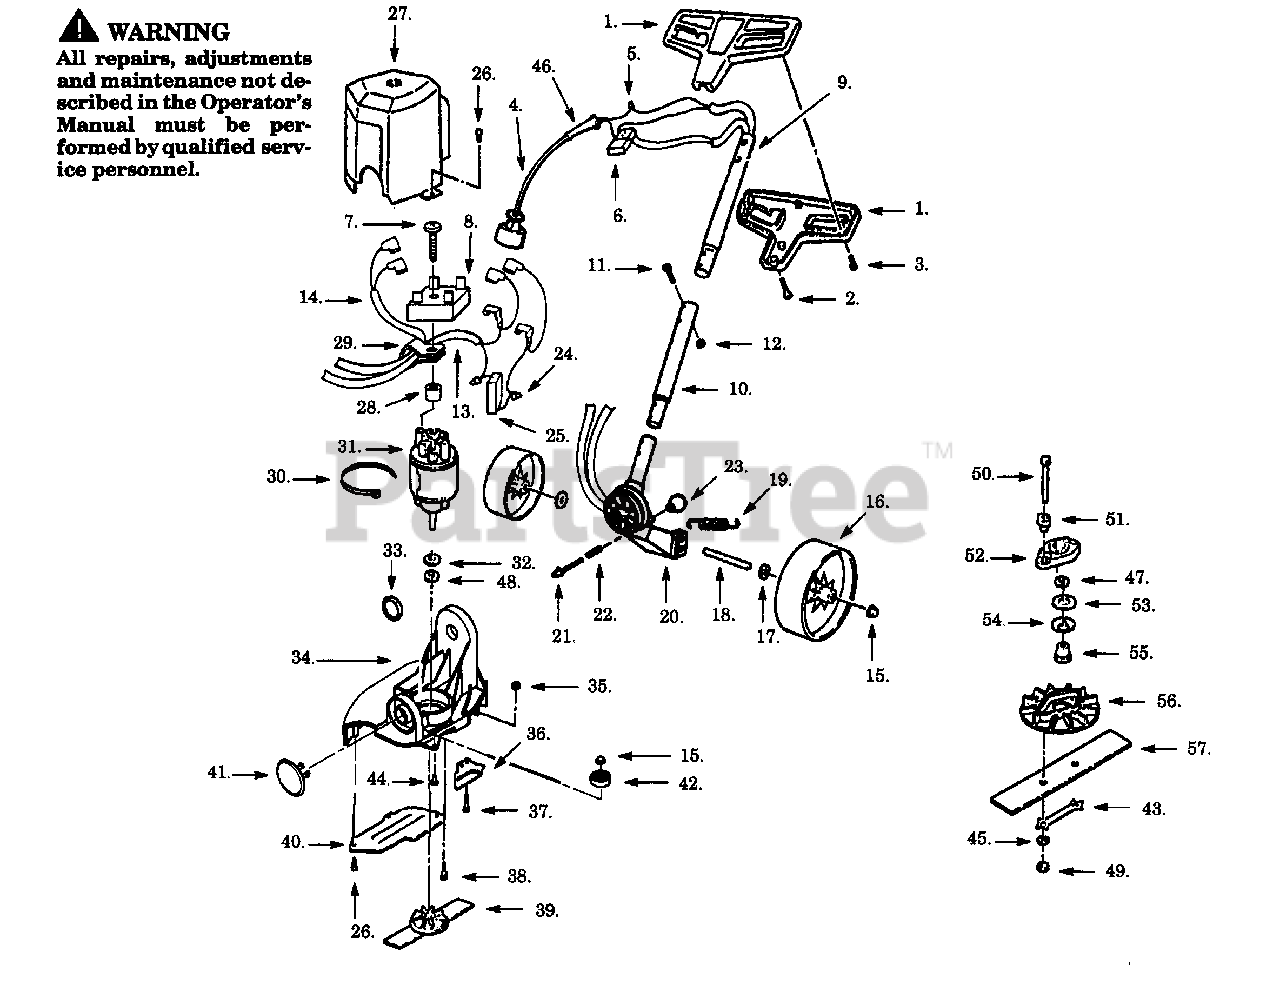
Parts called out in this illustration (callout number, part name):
1	Handle Set, Type 1
1	Handle Set, Type 2 Handle/ Cord Kit (Inc. 1, 4 & 46) See
4	Power Cord, Type 1
4	Power Cord, Type 2
5	Wire Nut
9	Upper Tube
10	Lower Tube
12	Locknut
13	Harness Ass'y. (Red/White)
14	Harness Ass'y. (Blue/White)
15	Push Nut
16	Rear Wheel
18	Rear Axle
20	Rear Swivel
21	Pin-Index
22	Swivel Lock Spring
24	Terminal Cap
25	Resister
27	Motor Cover
30	Tie Wrap
31	Motor Ass'y.
33	Retaining Ring
34	Deck Frame
36	Blade Guide
39	Blade Ass'y.
40	Side Guard Plate
43	Lock Strap
45	Lockwasher
51	Insulating Sleeve
52	Clutch Plate
54	Spring Washer
55	Clutch Sleeve
